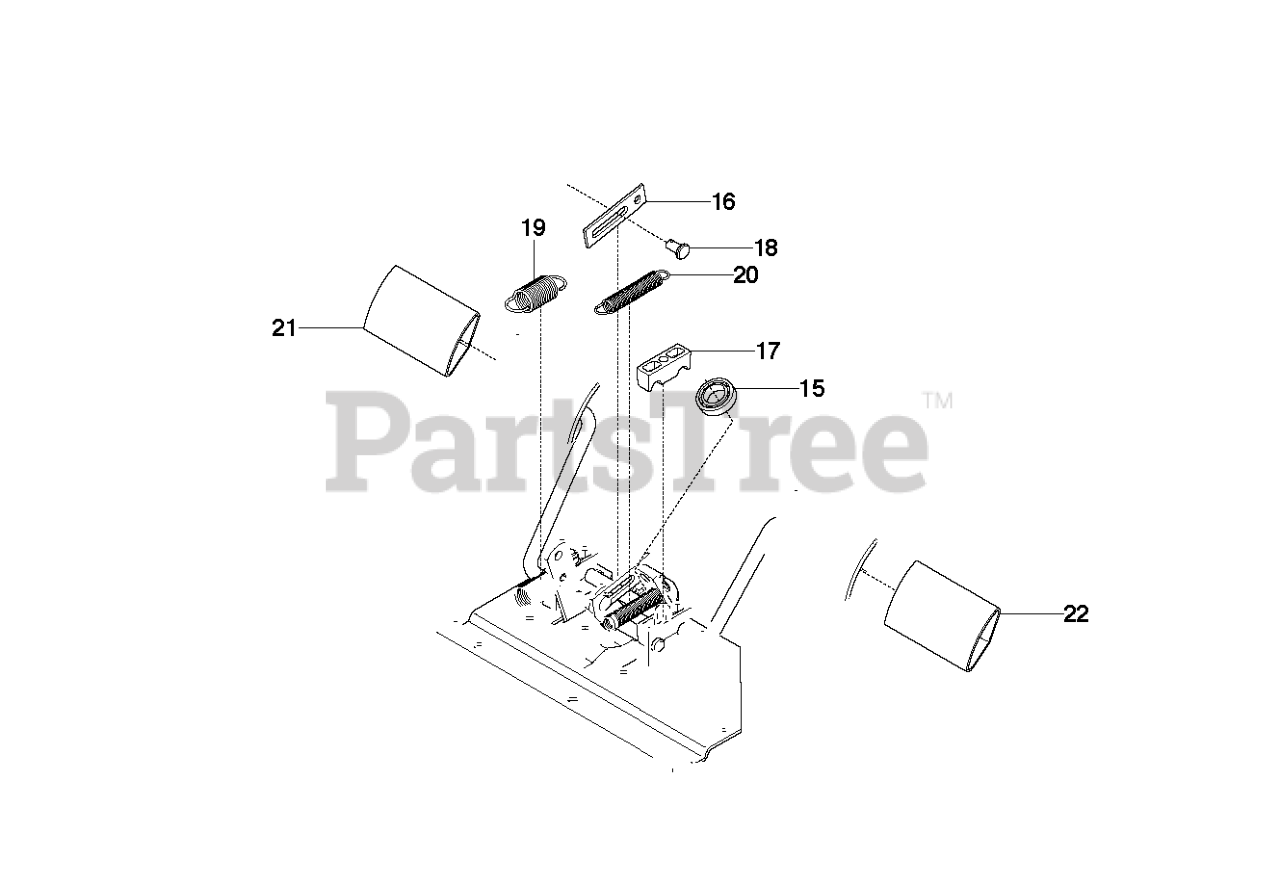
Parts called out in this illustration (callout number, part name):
15	BALL BEARING 6002-2RS1
17	PEDAL SHAFT CLAMP
18	Clevis Pin
21	PEDAL RUBBER, SF
22	PEDAL RUBBER, SF
